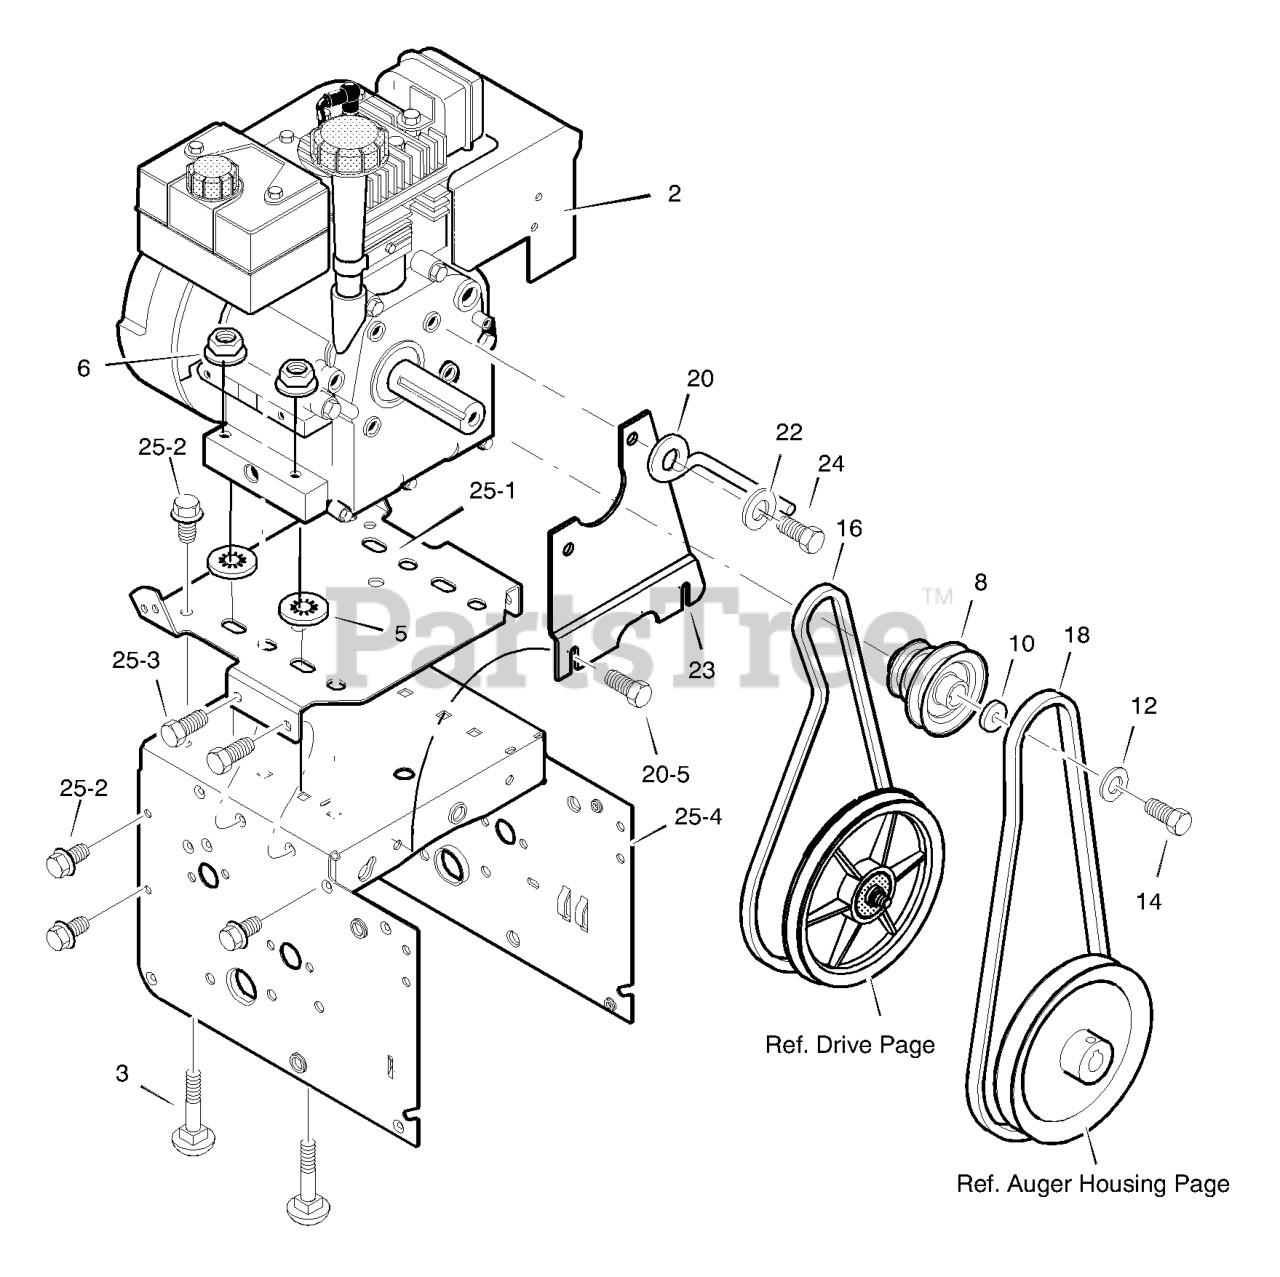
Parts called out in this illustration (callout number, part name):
2	ENGINE
3	BOLT, CARRIAGE 5/16-18
5	RETAINER, PUSH
6	NUT, HEX 5/16-18
8	PULLEY, ENGINE
10	WASHER
12	WASHER .38ID
14	SCREW, 3/8-24 x 1.00
16	BELT, V 3L 33.13LG
18	BELT, V 4L 38.1MF16" 5-10
20	GUIDE, BELT
22	WASHER, SPTLK .31X.58X.08
23	PLATE, ANTI VIBRATION
24	SCREW, 5/16-24 x 1.00
25	FRAME ASSEMBLY
25-1	PLATE, ENGINE MOUNT
25-2	SCREW, TAP 1/4-20 X .63
25-3	SCREW, TAP 5/16-18 X .50
25-4	FRAME, MOTOR BOX
